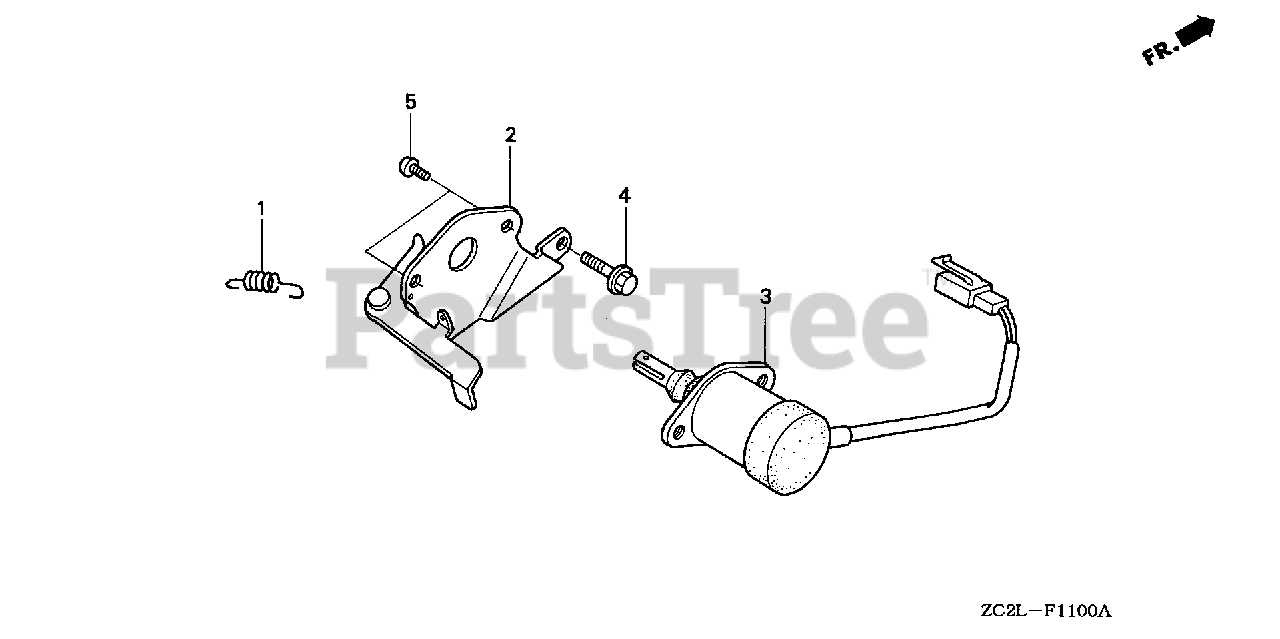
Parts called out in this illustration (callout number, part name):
1	SPRING, CHOKE RETURN
2	LEVER, THROTTLE
3	SOLENOID ASSY.
4	BOLT, FLANGE (6X12) (CT200)
5	SCREW, PAN (5X8)
